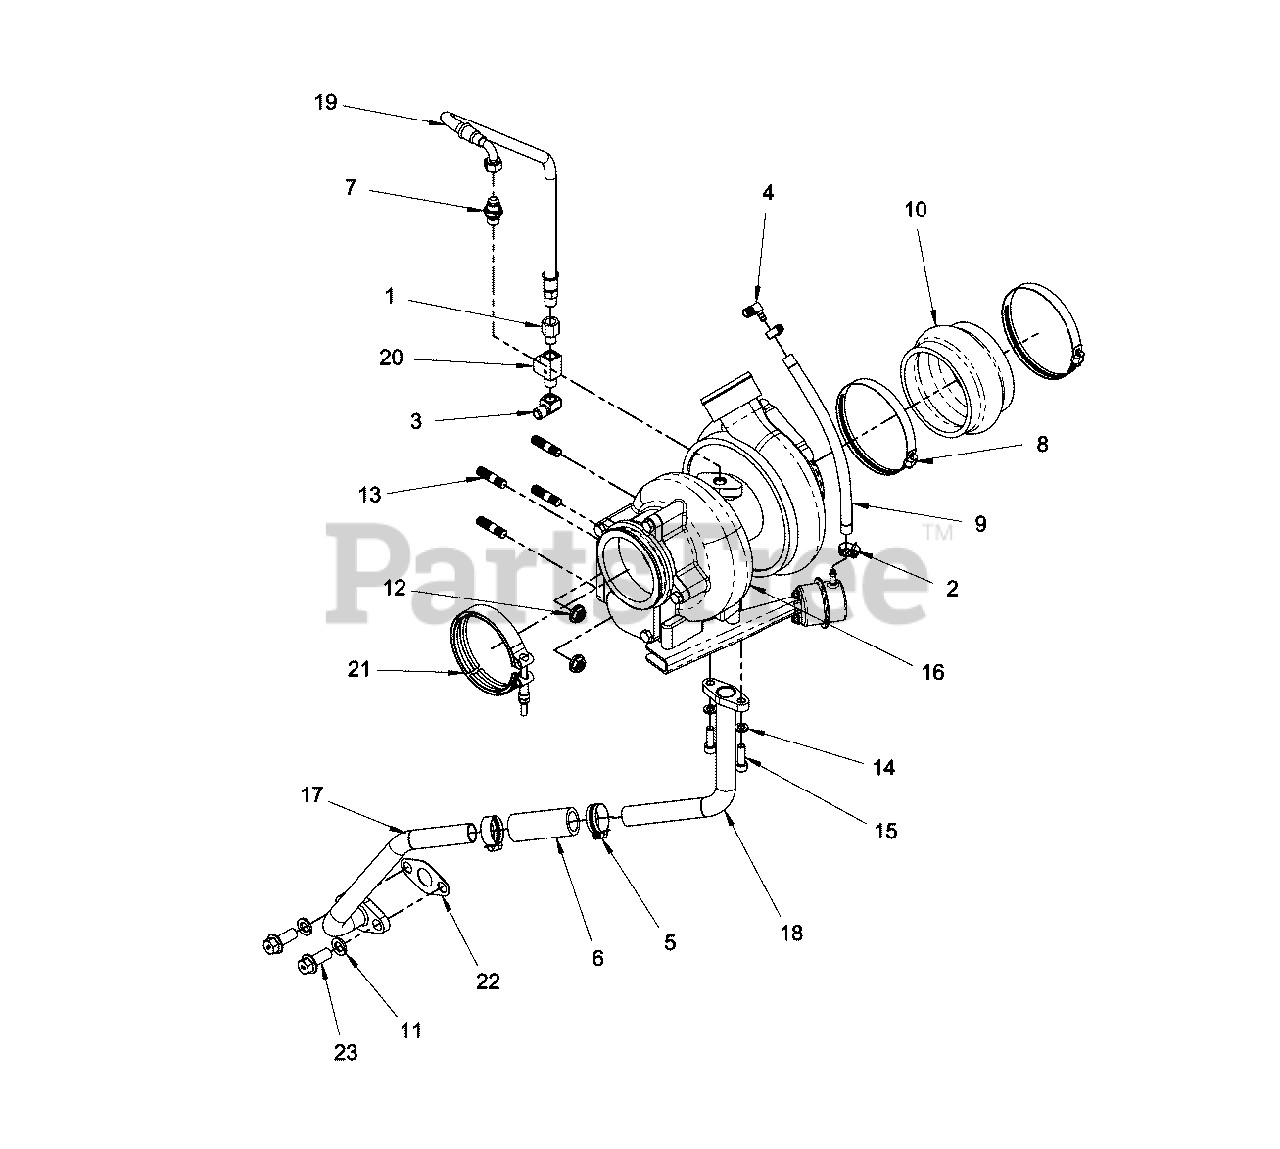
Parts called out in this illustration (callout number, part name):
1	* FITTING
2	CLAMP
3	ELBOW
4	* FITTING
5	CLAMP
6	HOSE
7	* FITTING, 3 IN
8	CLAMP
9	HOSE, 10 IN
10	HOSE
11	* WASHER
12	* NUT
13	* STUD
14	* WASHER
15	* BOLT
16	TURBOCHARGER
17	* TUBE
18	* TUBE
19	HOSE
20	* TEE
21	CLAMP
22	GASKET
23	* BOLT
